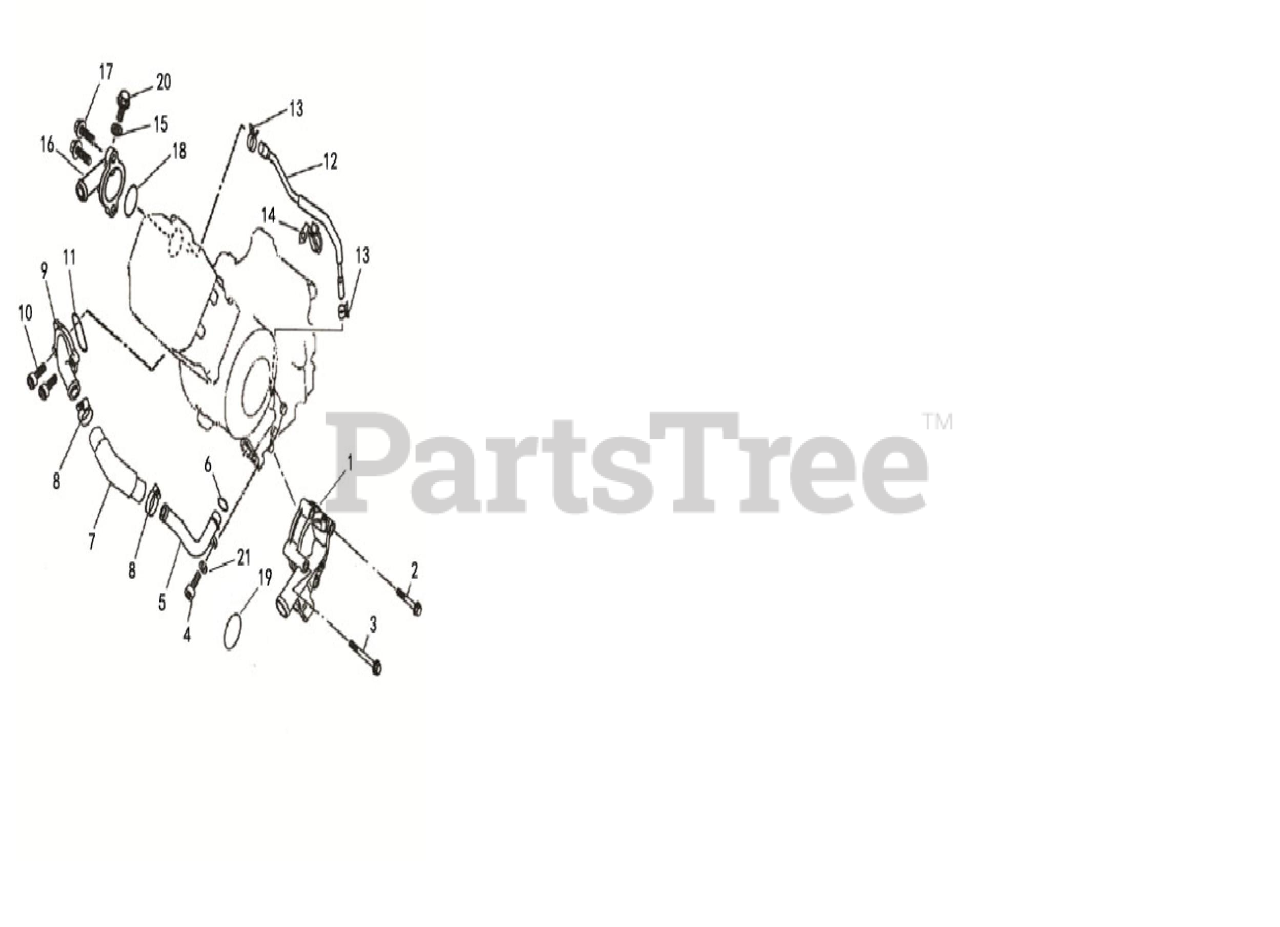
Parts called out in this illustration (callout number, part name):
1	Water Pump Assy
2	Hex flange bolts M6X45
3	Hex flange bolts M6X65
4	Hex flange bolts M6X16
5	Water pipe ?
6	O-Ring 20.7X2.6
7	Hose,Cylinder?Water In
8	Screw Clip D
9	Hose Joint,Cylinder,Water Out
10	Hex flange bolts M6X20
11	O-Ring 33.4X2.4
12	Water pipe ?
14	Pipe Clamp ?
15	Aluminum Washer 6X12X1.5
16	Cover,Thermostat
17	Hex flange bolts M6X20
18	Seal,thermostat cover
19	O-Ring 34.2X2.5
20	Hex flange bolts M6X12
21	Spring Washer 6
